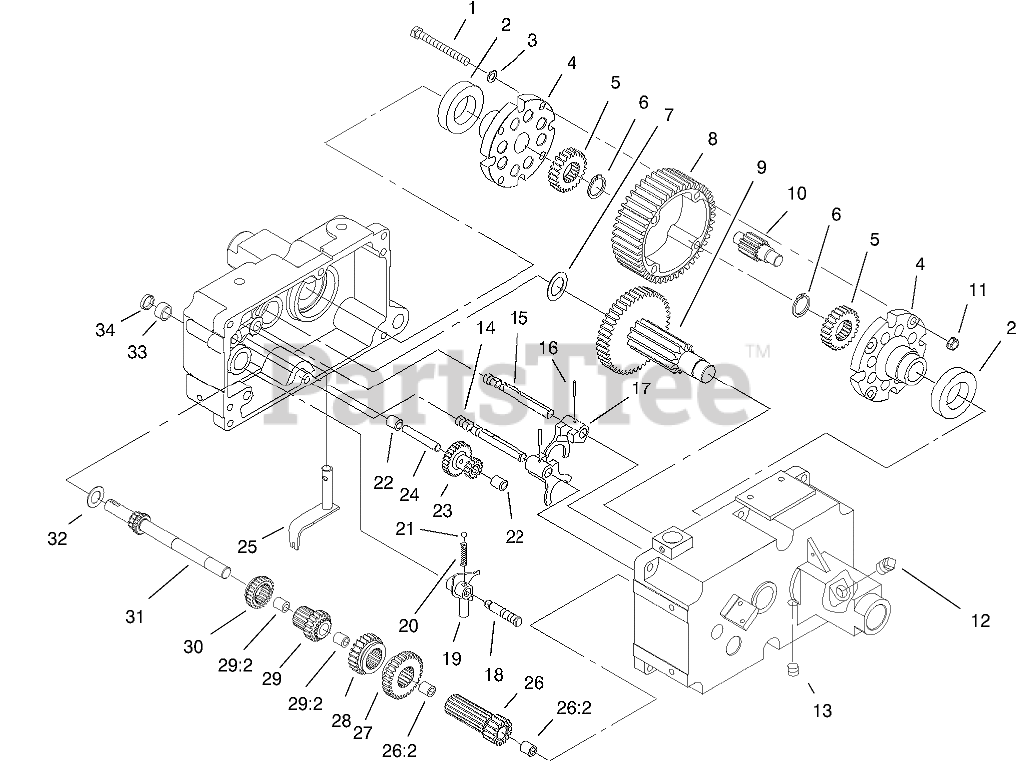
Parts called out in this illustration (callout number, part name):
1	BOLT-HEX
2	BEARING-BALL
3	WASHER
4	END CAP-DIFFERENTIAL
5	GEAR-AXLE DIFFERENTIAL
6	RING-SNAP
7	WASHER-THRUST
8	GEAR-DIFFERENTIAL RING, 43T
9	GEAR ASM
10	GEAR-PINION, 11T
12	PLUG-PIPE, SQH
13	PLUG-PIPE
14	RAIL-SHIFT
15	RAIL-REAR SHIFT
16	PIN-ROLL
17	FORK-SHIFT
18	BOLT-DETENT
19	SHIFT FORK ASM
20	SPRING-SHIFT STOP
21	BALL-DETENT
22	BEARING-NEEDLE
23	Gear
24	GEAR-SHAFT REDUCTION
25	SHIFT ASM
26	GEAR
26:2	BEARING-NEEDLE
27	GEAR-LOW AND REVERSE
28	GEAR-HI AND 2ND
29	GEAR
29:2	BEARING-NEEDLE
30	GEAR-SLIDING
31	SHAFT-INPUT
32	WASHER-THR
33	BEARING-NEEDLE
34	SEAL-OIL
